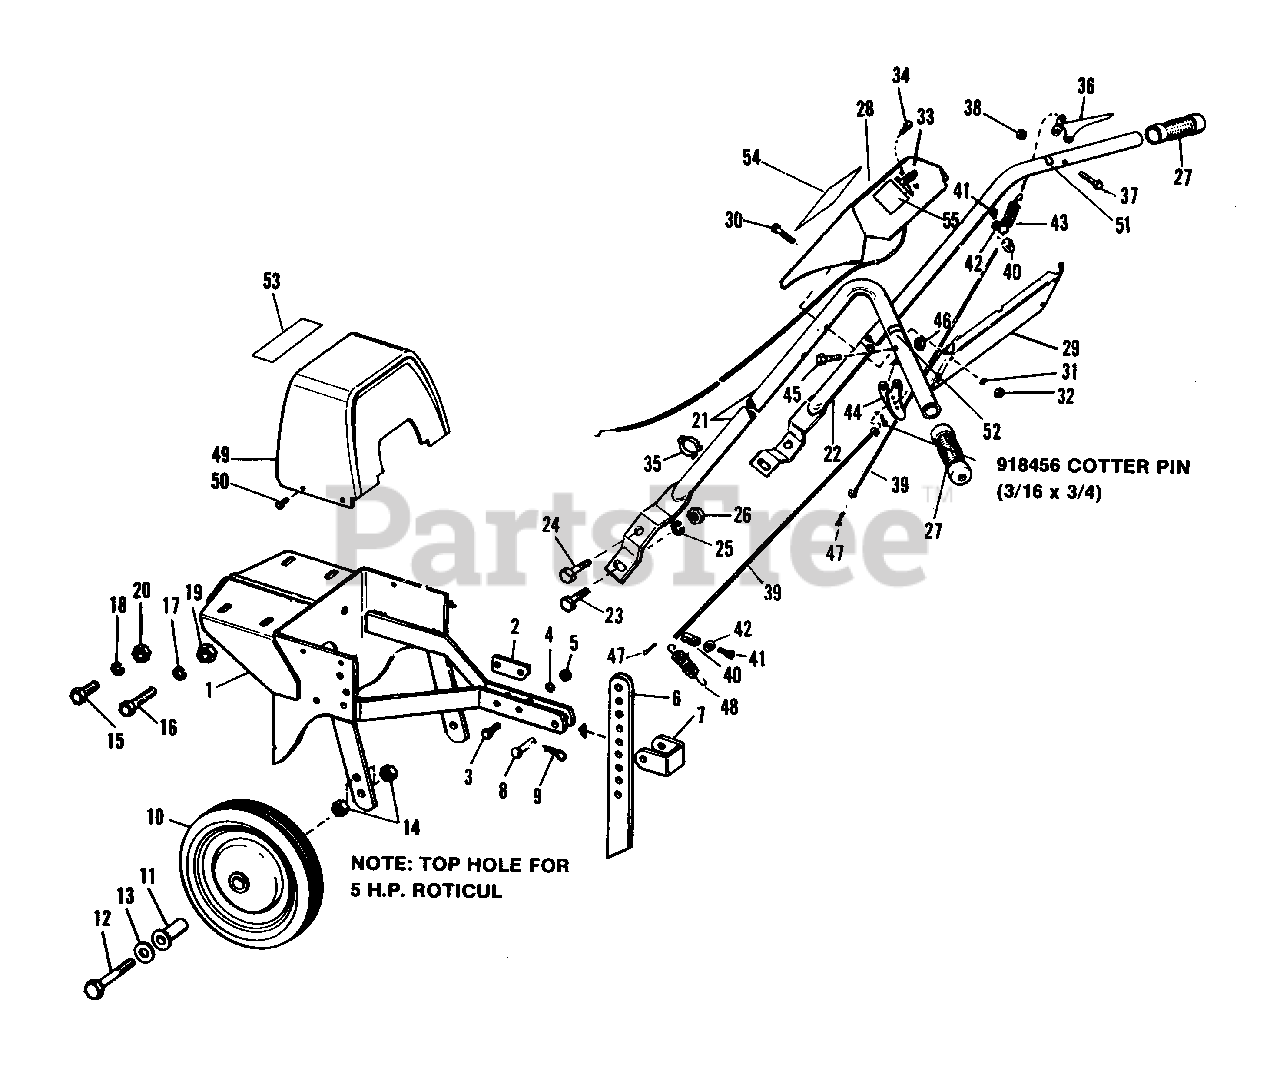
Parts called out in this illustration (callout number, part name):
1	BODY ASSY
2	PLATE, Stop
3	CAPSCREW, Hex, 3/8-16 x 1-1/2
4	LOCKWASHER, 3/8
5	NUT, Hex, Full, 3/8-16
6	BAR, Depth
9	CLIP, Spring
10	WHEEL & TIRE ASSY
11	BUSHING, Wheel
12	CAPSCREW, Hex, 1/2-13 x 3
13	WASHER, Plain, 1/2
14	NUT, Hex, Jam, 1/2-13
15	CAPSCREW, Hex, 3/8-16 x 3/4
16	CAPSCREW, Hex, 7/16-20 x 1-1/4
17	LOCKWASHER, 7/16
18	LOCKWASHER, 3/8
19	NUT, Hex, Full, 7/16-20
20	NUT, Hex, Full, 3/8-16
21	HANDLE, L.H.
22	HANDLE, R.H.
23	CAPSCREW, Hex, 3/8-16 x 1-1/4
24	SCREW, Hex, Whiz Lock, 3/8-16 x 1
25	LOCKWASHER, 3/8
26	NUT, Hex, Full, 3/8-16
28	HOUSING ASSY, Control
29	COVER, Handle, Upper
30	CAPSCREW, Hex, 1/4-20 x 1-1/2
31	LOCKWASHER, 1/4
32	NUT, Hex, Full, 1/4-20
33	THROTTLE ASSY, Control
34	SCREW, Hex, Self-Tapping, 1/4-20 x 1/2
35	CLIP, Cable
36	GRIP, Clutch
37	CAPSCREW, Hex, 1/4-20 x 1-1/2
38	NUT, Hex, Full Lock, 1/4-20
40	CLAMP, Wire
41	SETSCREW, Sq. Hd. #10-24 x 5/8
42	WASHER, Flat, #10
44	GRIP, Clutch
45	CAPSCREW, Hex, 1/4-20 x 1-1/2
46	NUT, Hex, Full Lock, 1/4-20
47	PIN. Cotter, 3/16 x 1
50	SCREW, Washer Hd., Taptite, 1/4-20 x 3/8
51	FILM, Tiller Clutch
52	FILM, Tiller Clutch
53	FILM, Simplicity
54	EMBLEM, "S"
55	DECAL, Throttle
